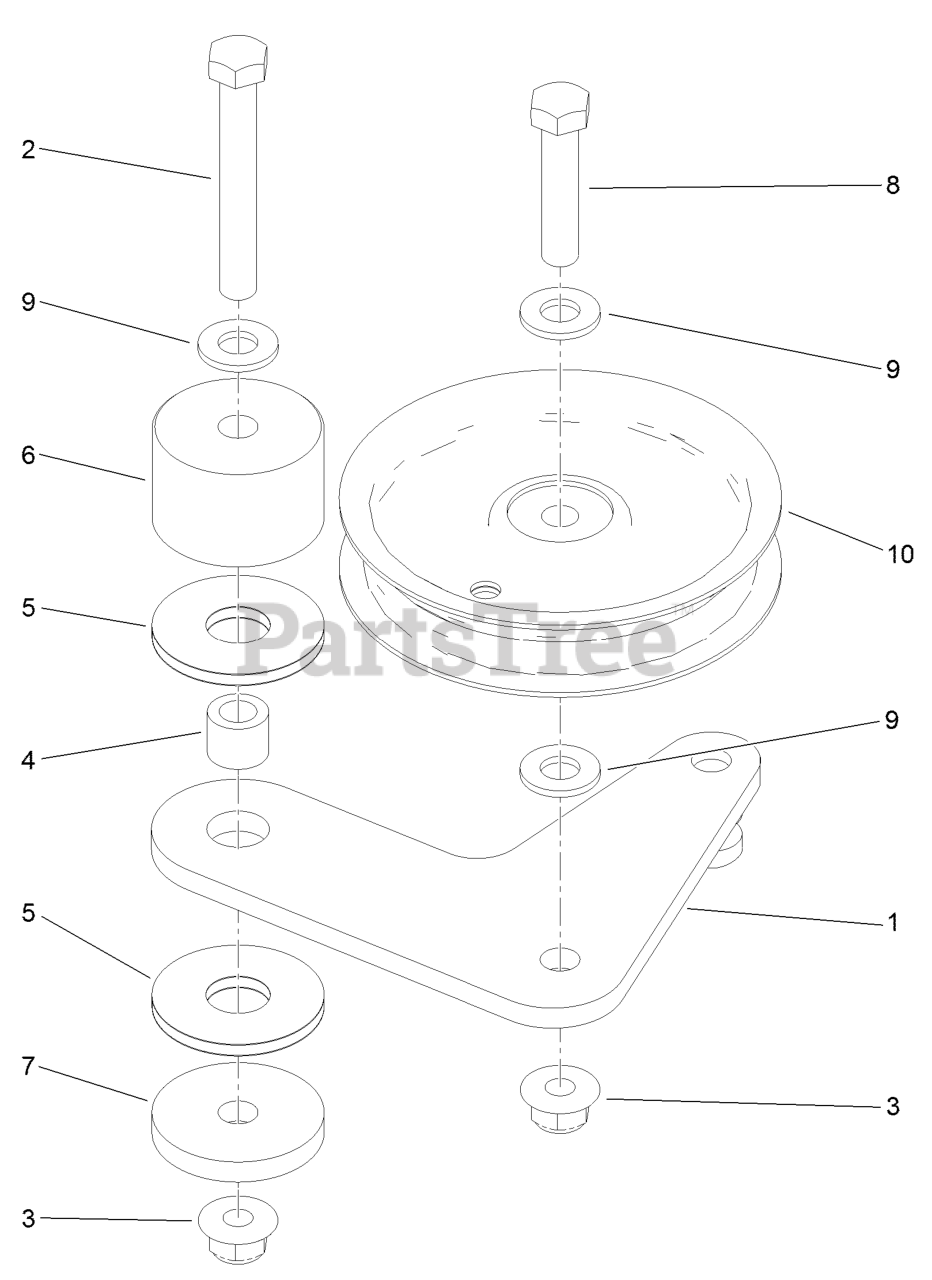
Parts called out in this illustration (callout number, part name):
1	PLATE-IDLER
2	SCREW-HH
3	NUT-HF, NI
4	BUSHING-LEVER, LIFT
5	WASHER-FRICTION, COMPOSIT
6	HUB-IDLER
7	WASHER-PLAIN
8	SCREW-HH
9	WASHER-FLAT
10	PULLEY-IDLER
